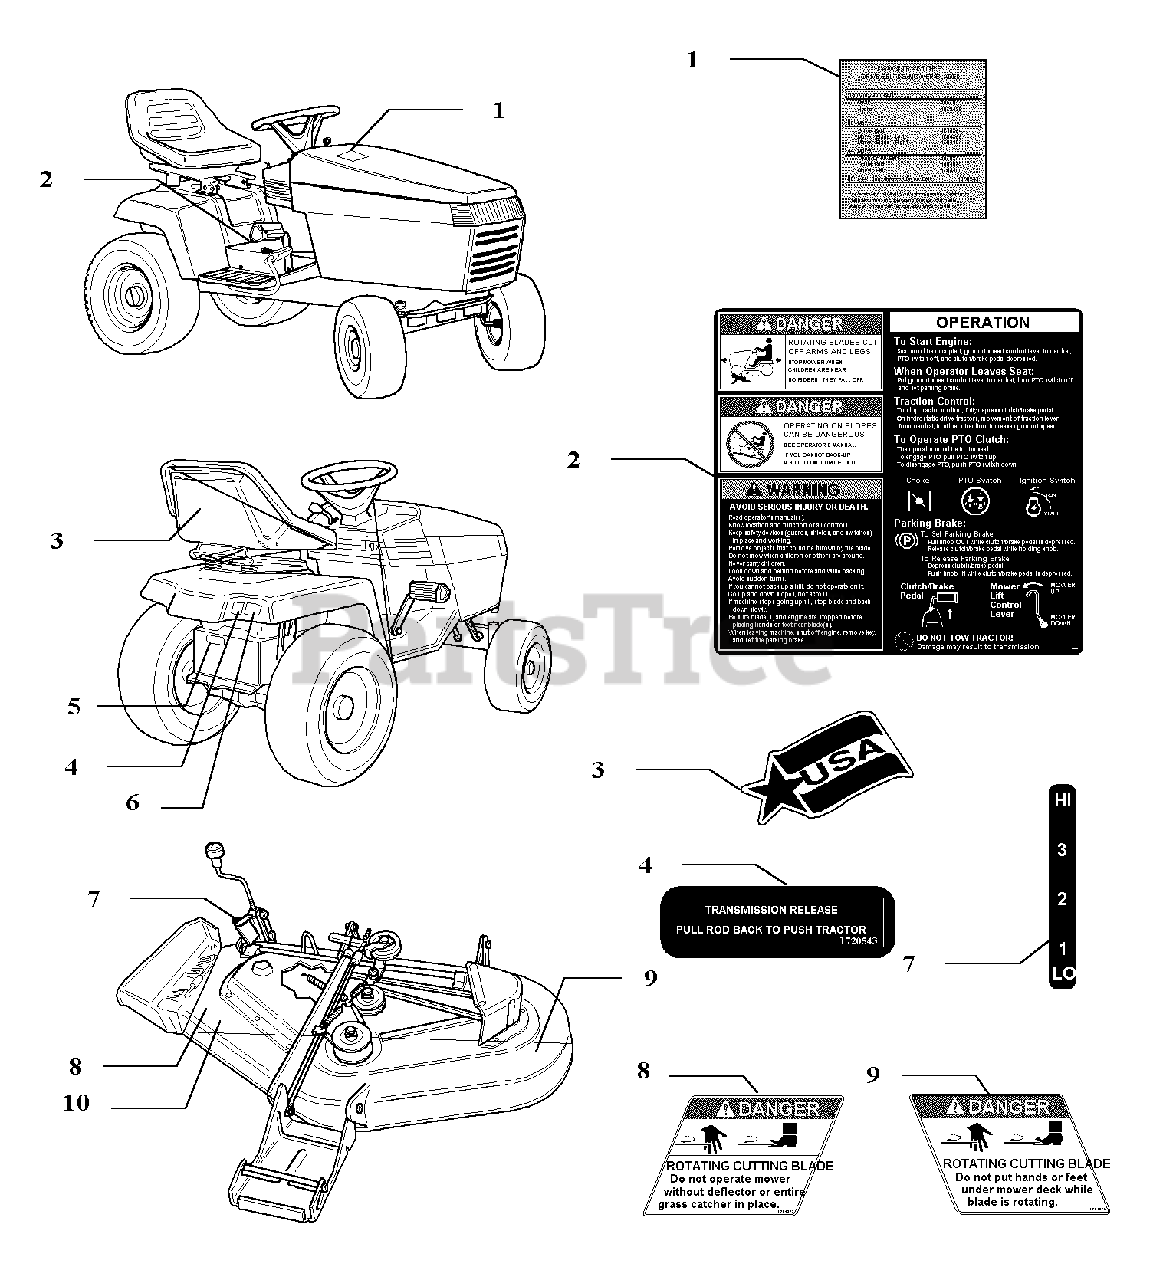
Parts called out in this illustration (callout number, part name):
1	DECAL, Belt, Blade
2	DECAL, Operating Instructions, Hand Control
3	DECAL, USA Logo
4	DECAL, CE (Export Models Only)
5	DECAL, Transmission Release Valve
6	DECAL, Power/Mass (Export Models Only)
7	DECAL, Mower Height
8	DECAL, Danger (Chute in place)
9	DECAL, Danger (Hand under deck)
10	DECAL, Cutting Width 44"
11	DECAL, OPEI (Not serviced)
12	I.D. PLATES (Not serviced)
